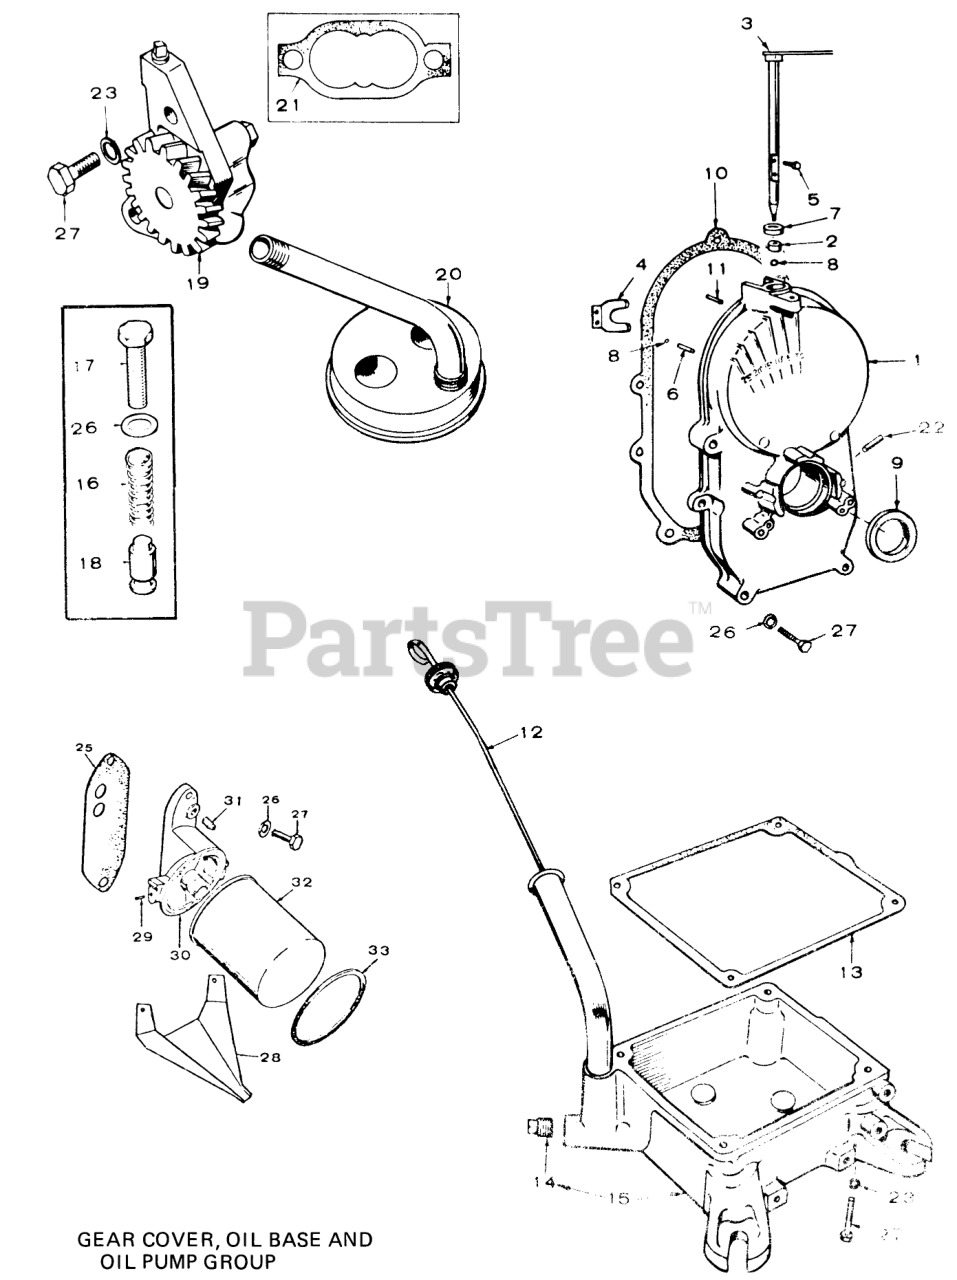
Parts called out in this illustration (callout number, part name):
1	COVER ASSEMBLY, GEAR (Includes Parts Marked )
2	Governor Shaft Bearing
3	Shaft and Arm Assy-Governor
4	Yoke-Governor Shaft
5	Yoke Retaining Screw
6	Pin,Governor-Cup Stop
7	Oil Seal-Governor Shaft
8	Ball Bearing-Governor Shaft
9	Seal-Gear Cover
10	Gasket-Gear Cover Mounting
11	Pin, Gear Cover (5/16 x 1/8)
12	OIL FILL-CAP&INDICTR
13	Oil Base Mounting Gasket
14	Oil Drain Plug
15	Oil Base
16	Spring-Oil By-Pass Valve
17	Screw-Oil By-Pass 3/8-24 X 1
18	Oil By-Pass Valve
19	Oil Pump-Complete
20	Intake, Oil Pump (Includes, Cup, Screen, and Pipe)
21	Oil Pump Gasket Kit
22	Fuel Pump Vacuum Tube
23	WASHER, LOCK
25	Gasket-Oil Filter Pad Cover
26	WASHER, FLAT
27	SCREW, HEX CAP
28	Dain, Oil Filter
29	Hex HD Screw With Et Washer
30	Oil Filter Adapter
31	Square HD Plug
32	Oil Filter
33	Oil Filter Air Seal
